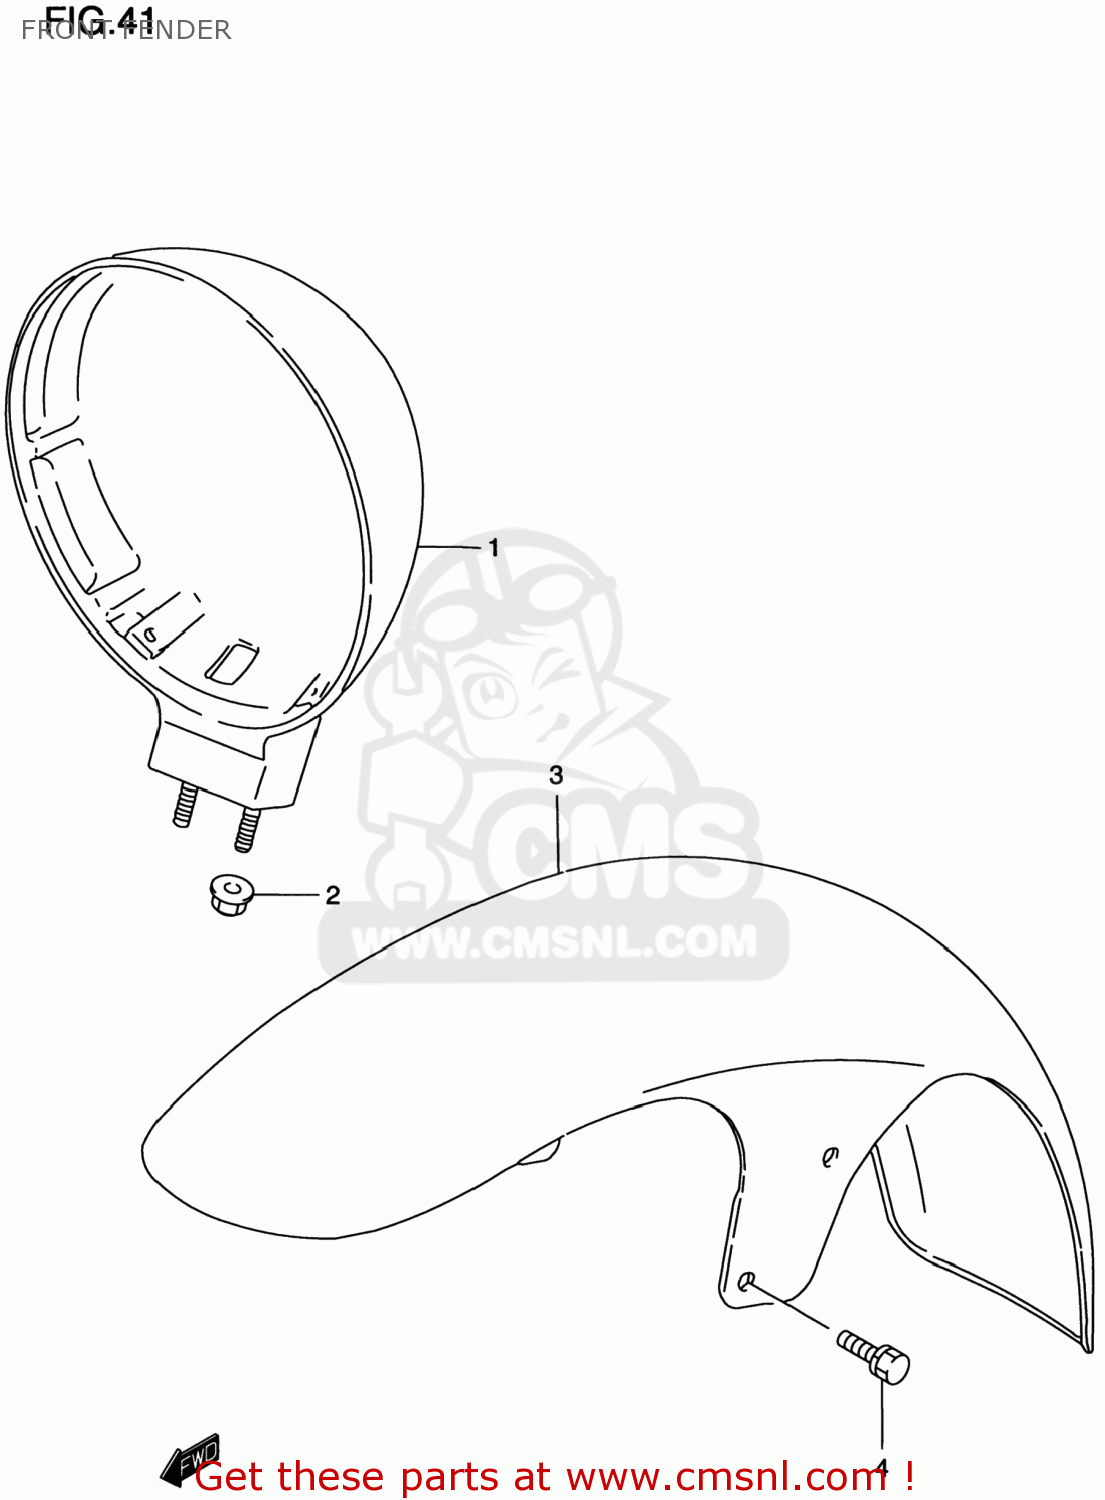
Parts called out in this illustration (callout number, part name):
1	HOUSING,HEADLAMP
2	NUT
3	FENDER,FR
4	BOLT
